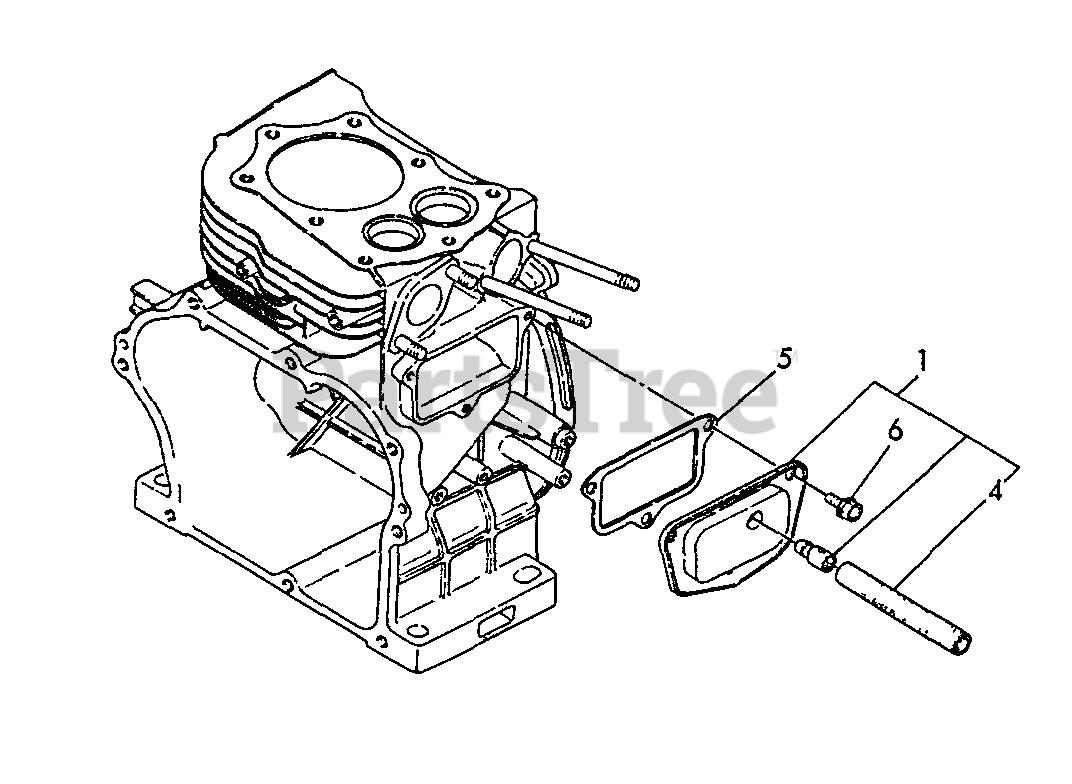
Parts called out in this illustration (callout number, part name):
1	BREATHER ASSY
4	PIPE, BREATHER
6	BOLT - 6×8 -- PLATED
